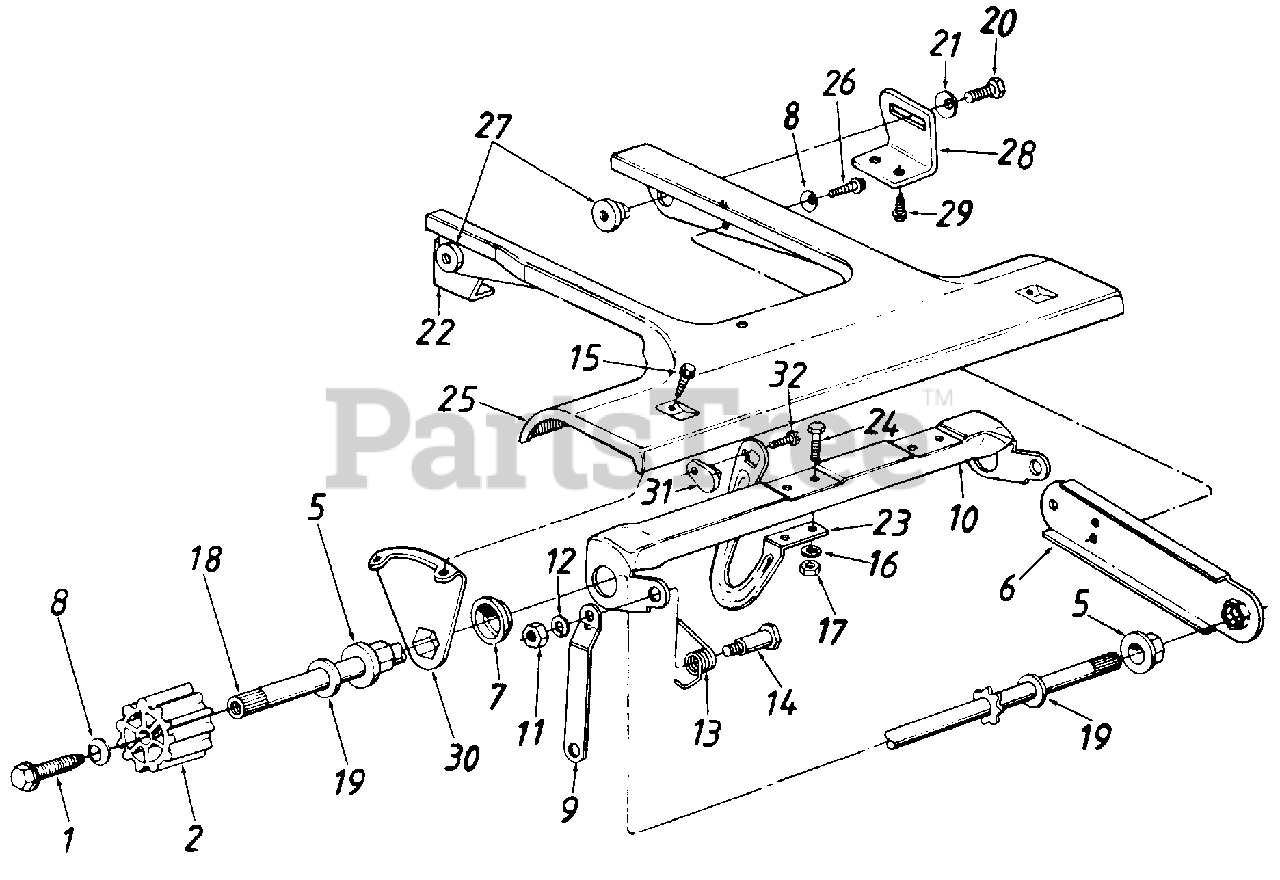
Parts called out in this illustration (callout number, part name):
1	Hex Wash. Hd. Tap Scr. 1/4-20 x .75" Lg.
2	Wheel Drive Pinion-Half
5	Hex Flange Brg. .504" I.D.
8	Bell-Wash. .265" I.D. x .75" O.D.
9	Link 5.06" Lg.
10	Drive Engagement Cam
11	Hex Nut 5/16-18 Thd.*
12	L-Wash. 5/16" I.D.
13	Torsion Spring-R.H.
14	Shoulder Bolt .437" Dia.
15	Hex AB-Tap Scr. 1/4" x .62" Lg.
16	L-Wash. 1/4" I.D.
17	Hex Nut 1/4-20 Thd.
18	Drive Shaft Ass'y.
19	Fl-Wash. .531" I.D. x .93" O.D.
20	Hex Bolt 5/16-18 x .62" Lg.
21	Bell-Wash. .345" I.D. x .88" O.D.
22	Pivot Bracket-R.H.
25	Front Pinion Pivot Cover
26	Hex B-Tap Scr. 1/4" x .38" Lg.
27	Shoulder Nut
28	Pivot Bracket-L.H.
29	Hex Wash. Hd. AB-Tap Scr. 1/4 x.62" Lg.
32	Hex B-Tap Scr. #10 x .441' Lg.
